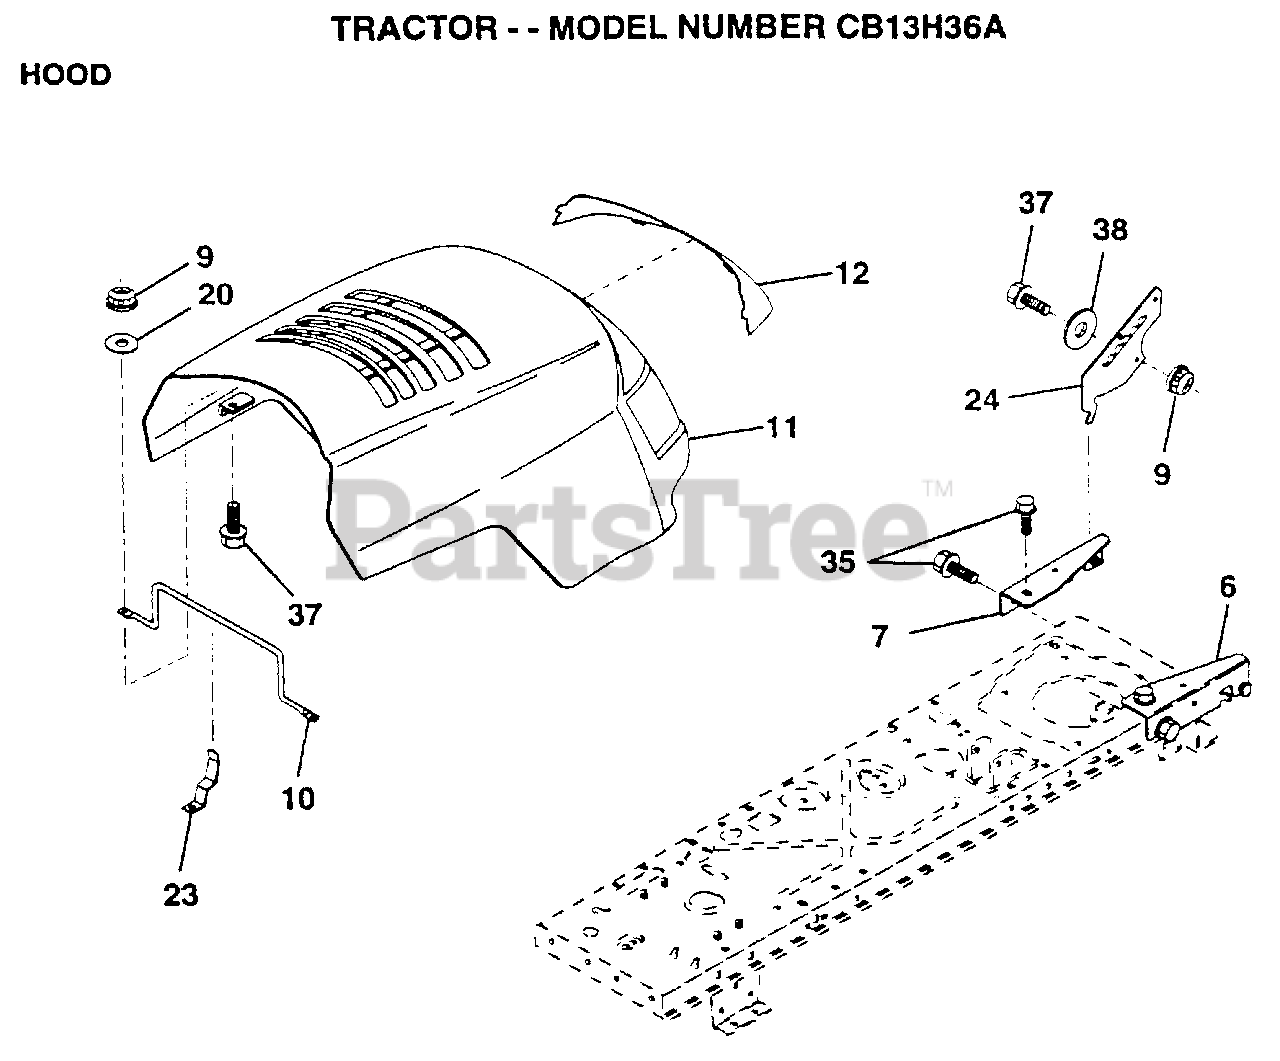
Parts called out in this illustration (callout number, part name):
6	BRACKET ASM HD RH
7	BRACKET ASM HD LH
9	NUT
10	ROD SUPT HOOD
11	HOOD/GRILLE.505
12	LENS.PL.BAR.CLEAR
20	WASHER
23	LATCH.HOOD.LR
24	BRACKET.PVT.HOOD
35	SCREW
37	BOLT LT
39	WASHER
